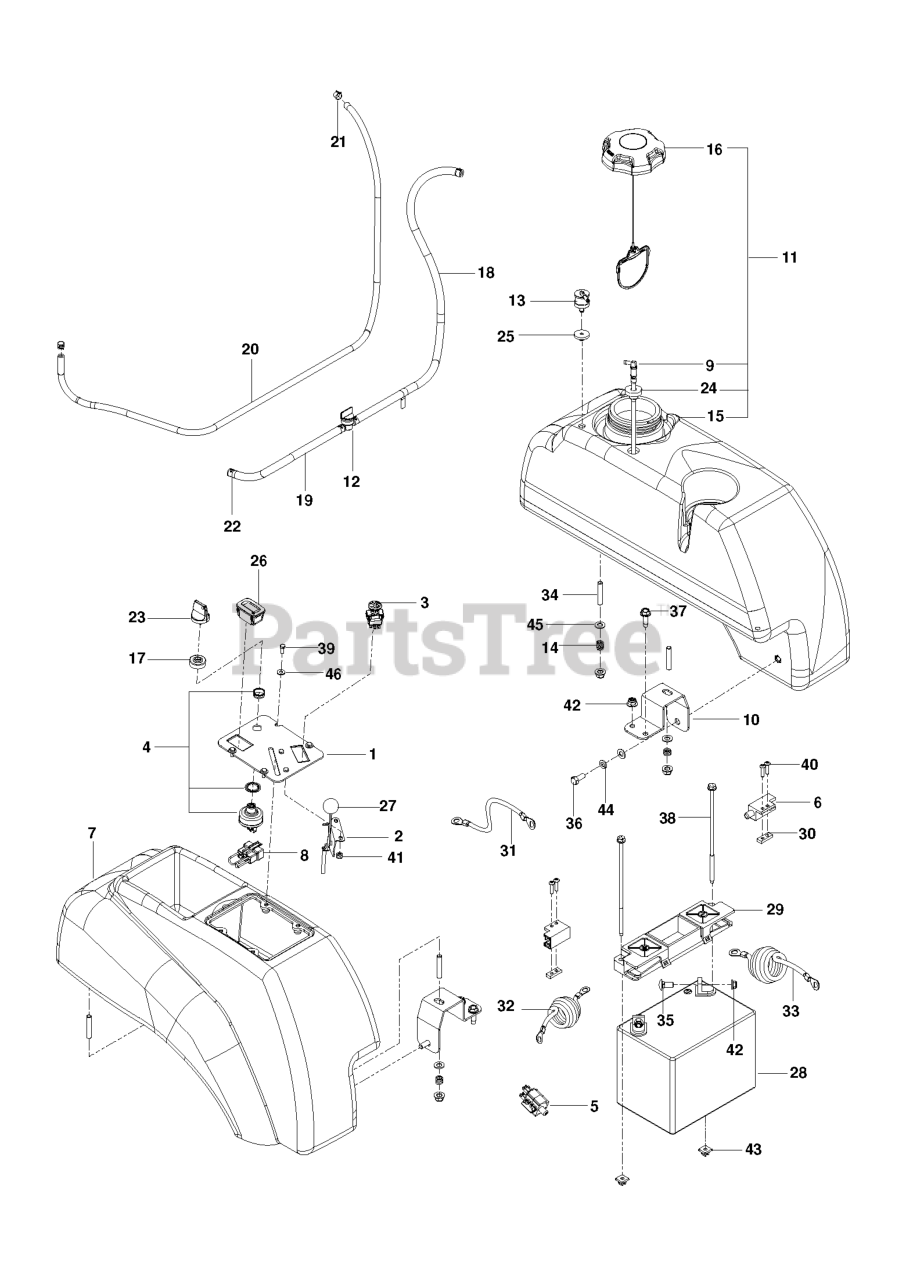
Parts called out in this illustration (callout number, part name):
1	RP.PLATE, CONSOLE, BLK
2	THROTTLE CABLE
3	RP SWITCH.PTO.TERMINAL.STD.RED
4	SWITCH, IGNITION, INDAK
5	SWITCH, BRAKE 3P
6	SWITCH INTERLOCKT
7	FENDER CONSOLE
8	PLUG, TIMER
9	FITTING, FUEL
10	SUPPORT, TANK, BLK
11	ASSEMBLY, LT TANK, EPA GRAY
12	FUEL VALVE
13	VALVE.FUEL.CHECK
15	TANK, FUEL, LT-EPA
16	CAP, FUEL
17	CAP IGNITION NUT
18	HOSE, FUEL .25 ID X 26"
19	GAS LINE 10"
20	HOSE, VAPOR 3/16 X 48"
21	CLAMP, HOSE
22	HOSE CLAMP
23	KEY, IGNITION
24	RUBBER GROMMET
25	GROMMET, CHECK VALVE
26	RP.GUAGE.SRVCMNDR.HRMTR.
27	KNOB.ROUND.BALL.BLACK
28	BATTERY, 12 V 330 AMP
29	BATTERY HOLD DOWN
30	TAPPED PLATE
31	CABLE POSITIVE
32	POST.CABLE LONG
33	NEG. CABLE, 28"
34	STUD, 5/16C
35	BOLT 5/16C X 3/4" CARRIAGE
36	HCS 5/16C X 3/4
37	RP BLT 5/16-18 X 1 THRD FORM D
38	BOLT - 1/4-20 X 7.5
39	HCS #10-24 X 1/2
40	SCR #10-24 X .75 SKT HD BLK
41	NUT 10-24 NYLOC
42	5/16-18 NYLOC FLANGE NUT
43	PUSH NUT-NYLON
44	WASHER.LOCK.HVY.HLCL.SPR.5/16
45	FLAT WASHER 5/16 SAE
46	WASHER #10
